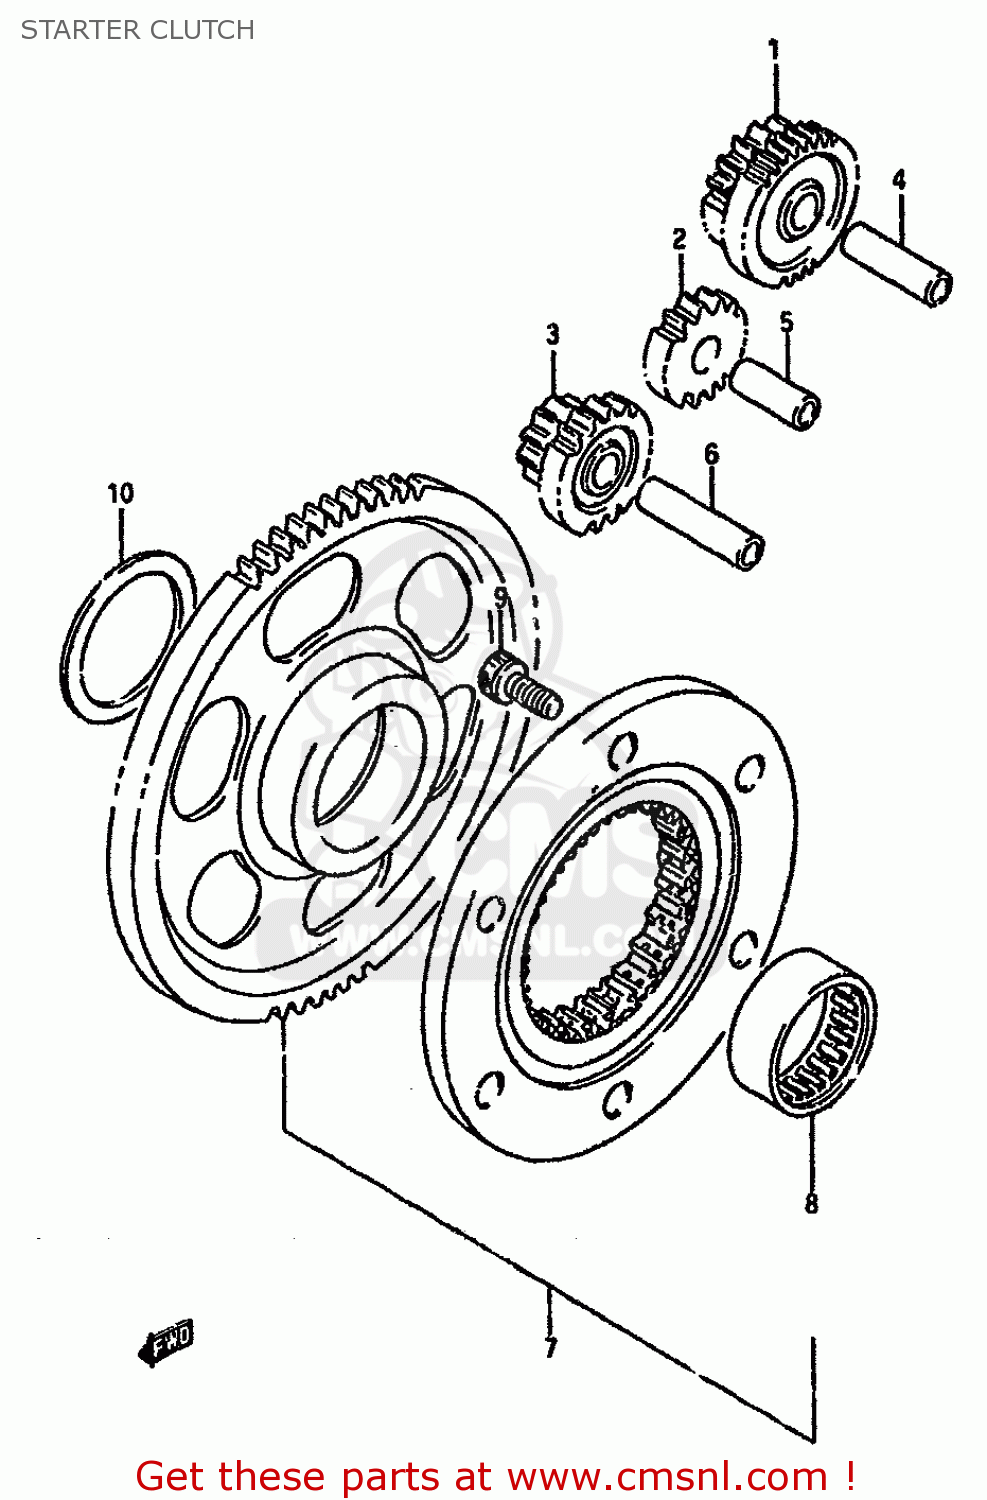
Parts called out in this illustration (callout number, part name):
1	GEAR,STARTER IDLE,NO.1
2	GEAR,STARTER IDLE,NO.2
3	GEAR,STARTER IDLE,NO.3
4	PIN
5	PIN
6	PIN
7	CLUTCH SET,STARTER
8	BEARING(35X43X18)
9	BOLT
10	WASHER
